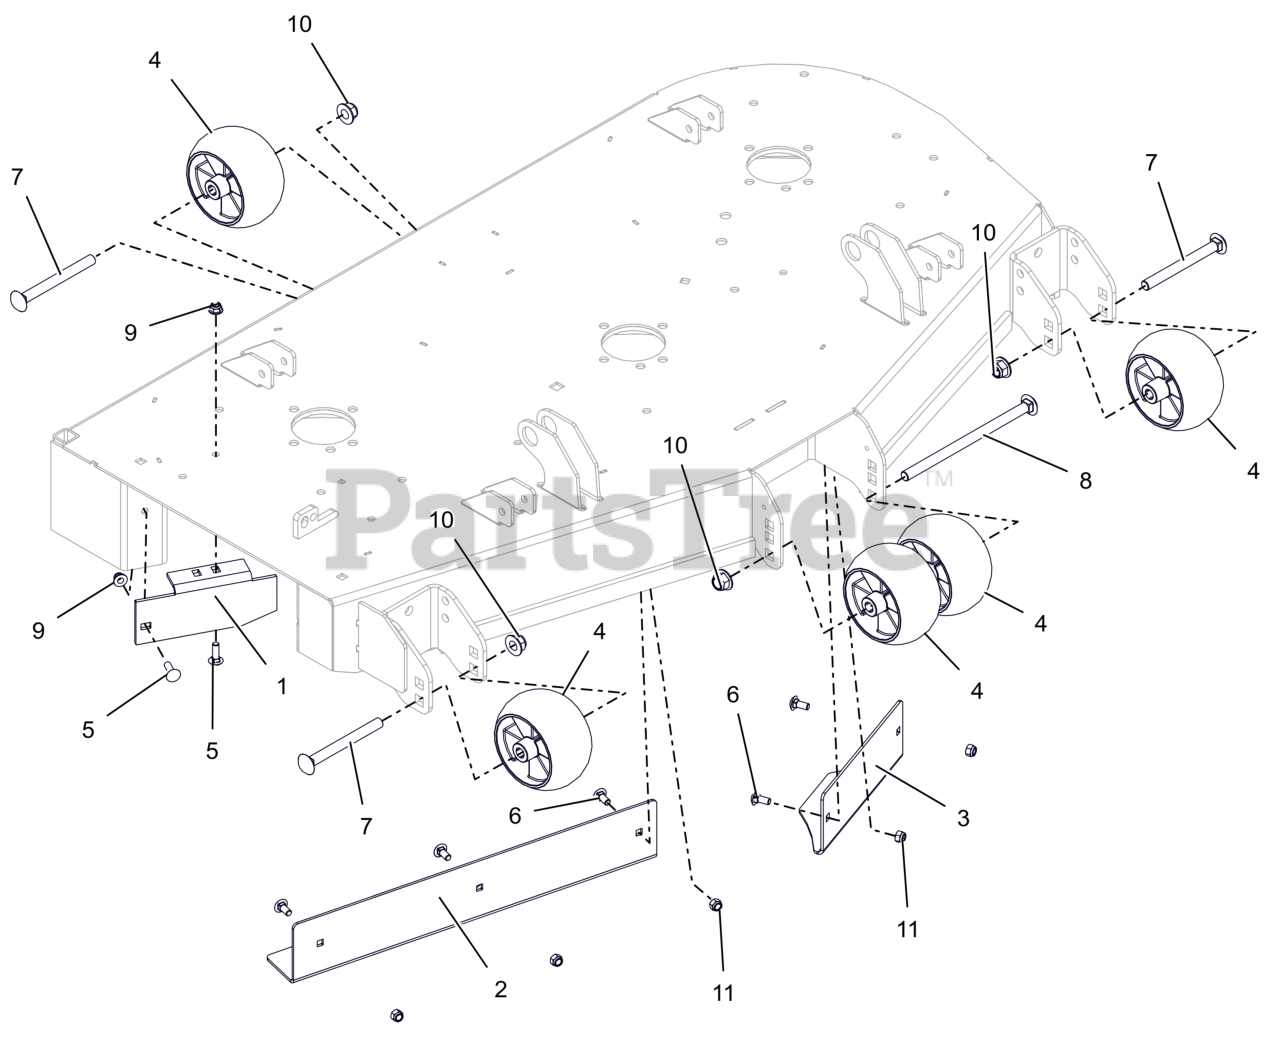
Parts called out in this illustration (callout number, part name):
1	BAFFLE, 44/48" SIDE DISCHARGE
2	BAFFLE, 48" RH VACUUM (ORANGE)
3	BAFFLE, 44/48" LH VACUUM (ORANGE)
4	WHEEL, ANTI SCALP - 5X3 CTR W/RIBS
5	BLT,RHSN .31-18X1.00 G5 ZCC
6	BLT,RHSN .31-18X.75 G5 ZCC
7	BLT, RHSN .50-13X5.00 G5 ZCC
8	BTL,RHSN .500-13 X 8.5S G5 ZCC
9	NUT,LK-NYL-FLG .31-18 G5ZC120
10	NUT,NYL-FLG .50-13 GF ZCC
11	NUT,NYL .31-18 G5 ZCC
